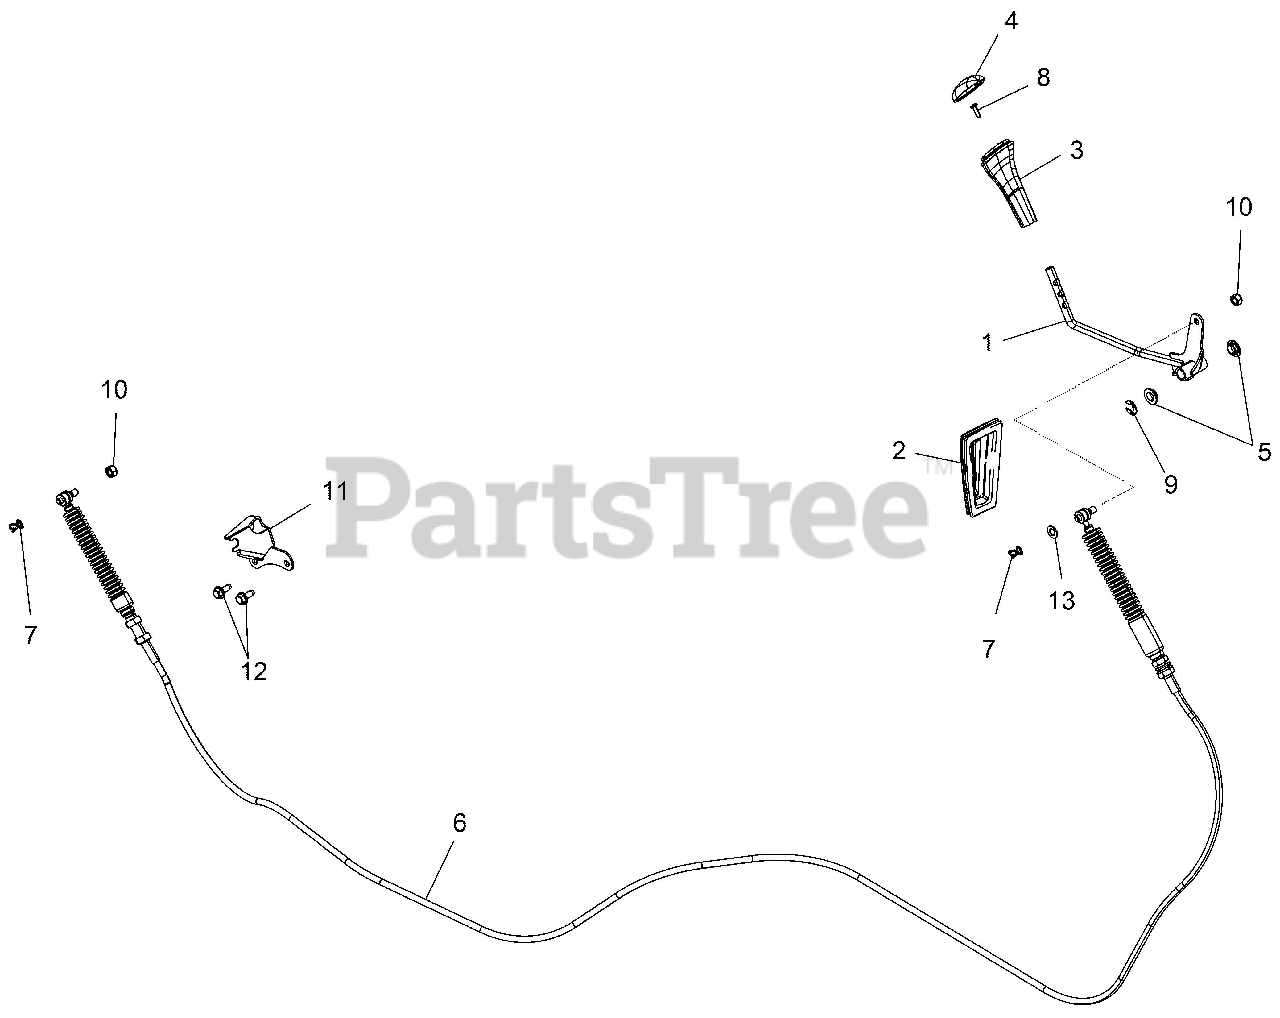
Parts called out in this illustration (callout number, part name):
1	WELD-SHIFT LEVER,BLK
2	GROMMET-SHIFT LEVER
3	KNOB-GEAR SELECTOR SHIFT
4	COVER-SHIFT
5	BUSHING-PEDAL PIVOT
6	CABLE, SHIFT
7	PIN-CLIP,14MM
10	NUT,NYLOK M8X1.25(10) *
11	BRKT-SHIFT CABLE
12	BOLT-M10X1.25X16,HXHD,FLG
13	WASHER,FLAT(10)
